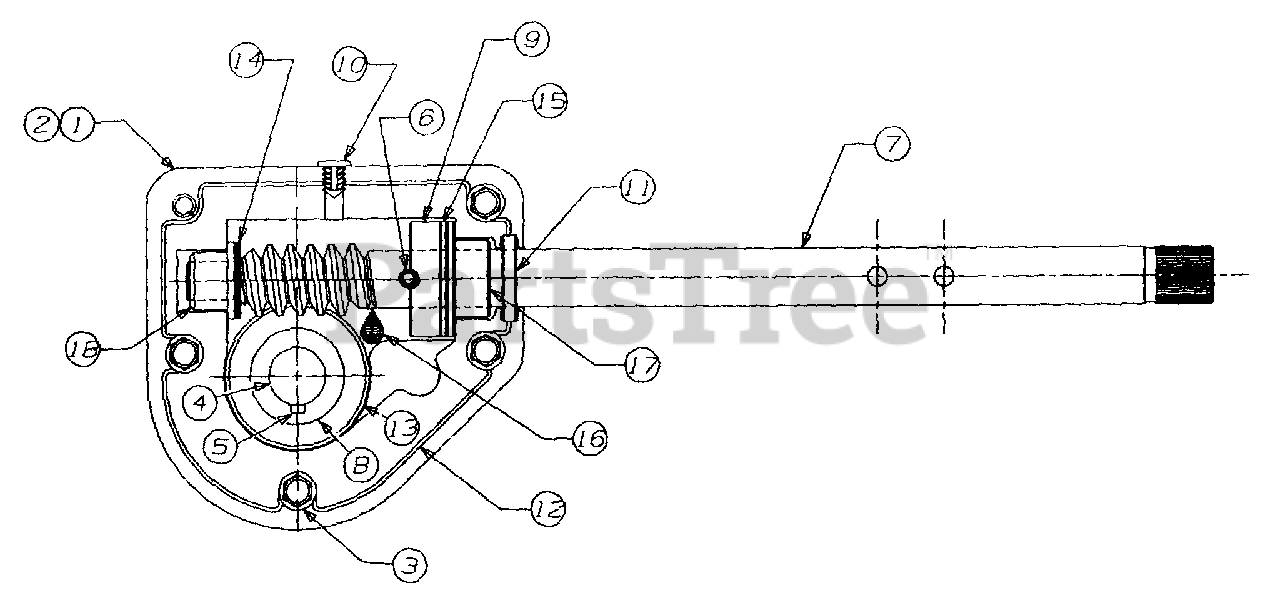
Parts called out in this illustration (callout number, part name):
1	Housing - R.H.
2	Housing - L.H.
4	Axle, Spiral 30" (1030E)
5	Key, Hi-Pro
6	Pin, Spiral
7	Worm, Shaft
8	Gear, Worm
9	Collar, Thrust
11	Seal, Oil
12	Loctite 5699
13	Washer - Flat
14	Washer - Flat
15	Washer - Flat
16	Grease
17	Bearing Flange
18	Bearing Flange
